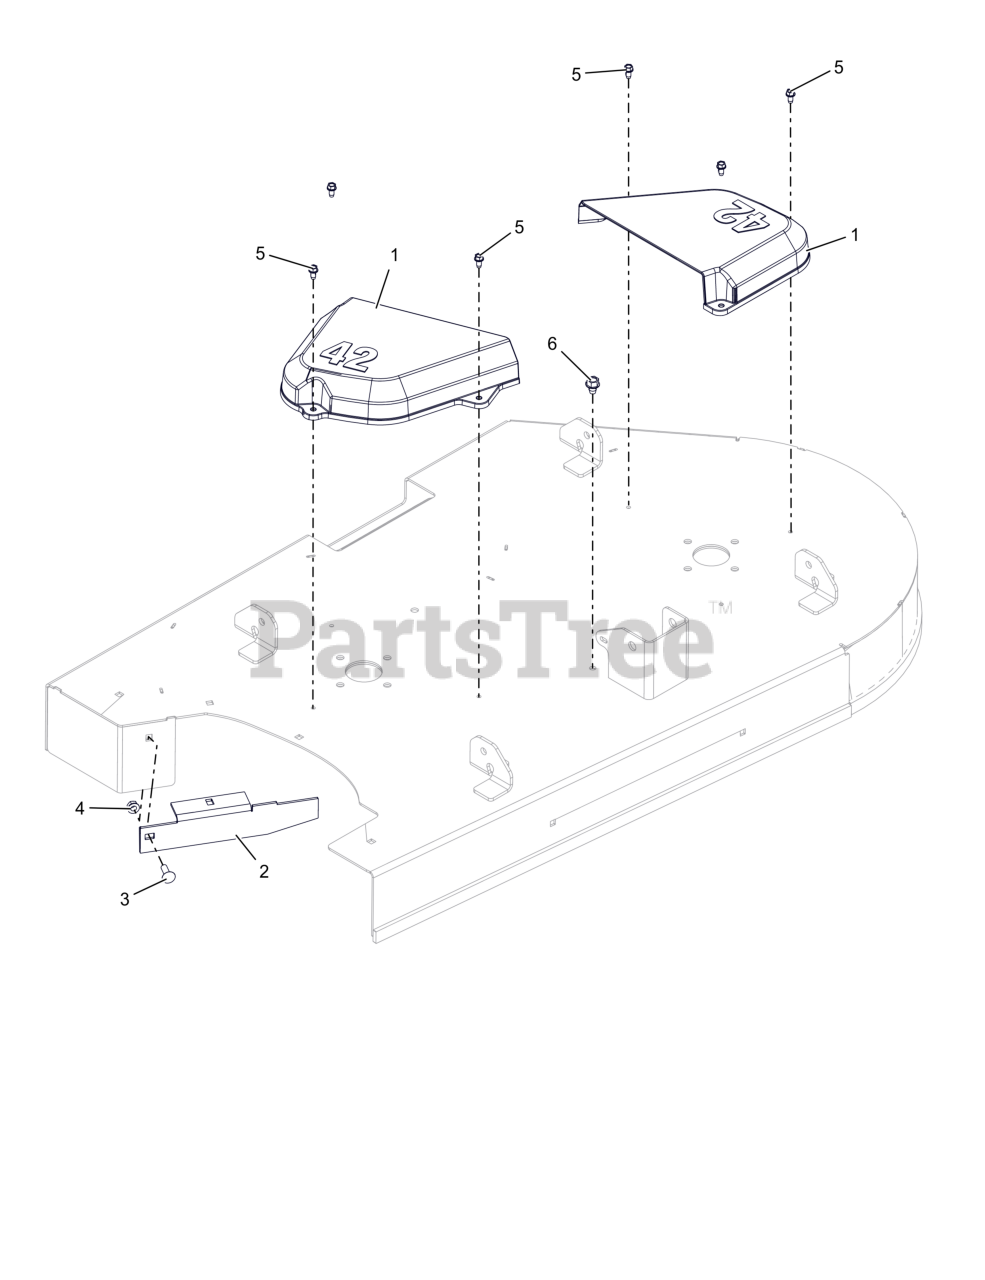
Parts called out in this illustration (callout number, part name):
1	COVER, BELT 42" RH
2	STRIP, DEFLECTOR (BLACK)
3	BLT,RHSN .31-18X1.00 G5 ZCC
4	NUT,LK-CTR-FLG .31-18 GF ZCC
5	SCR-TAP .25-20X.50 HWH ZCC
6	SCR,TAP .375-16X.50 HWH TR ZCC
